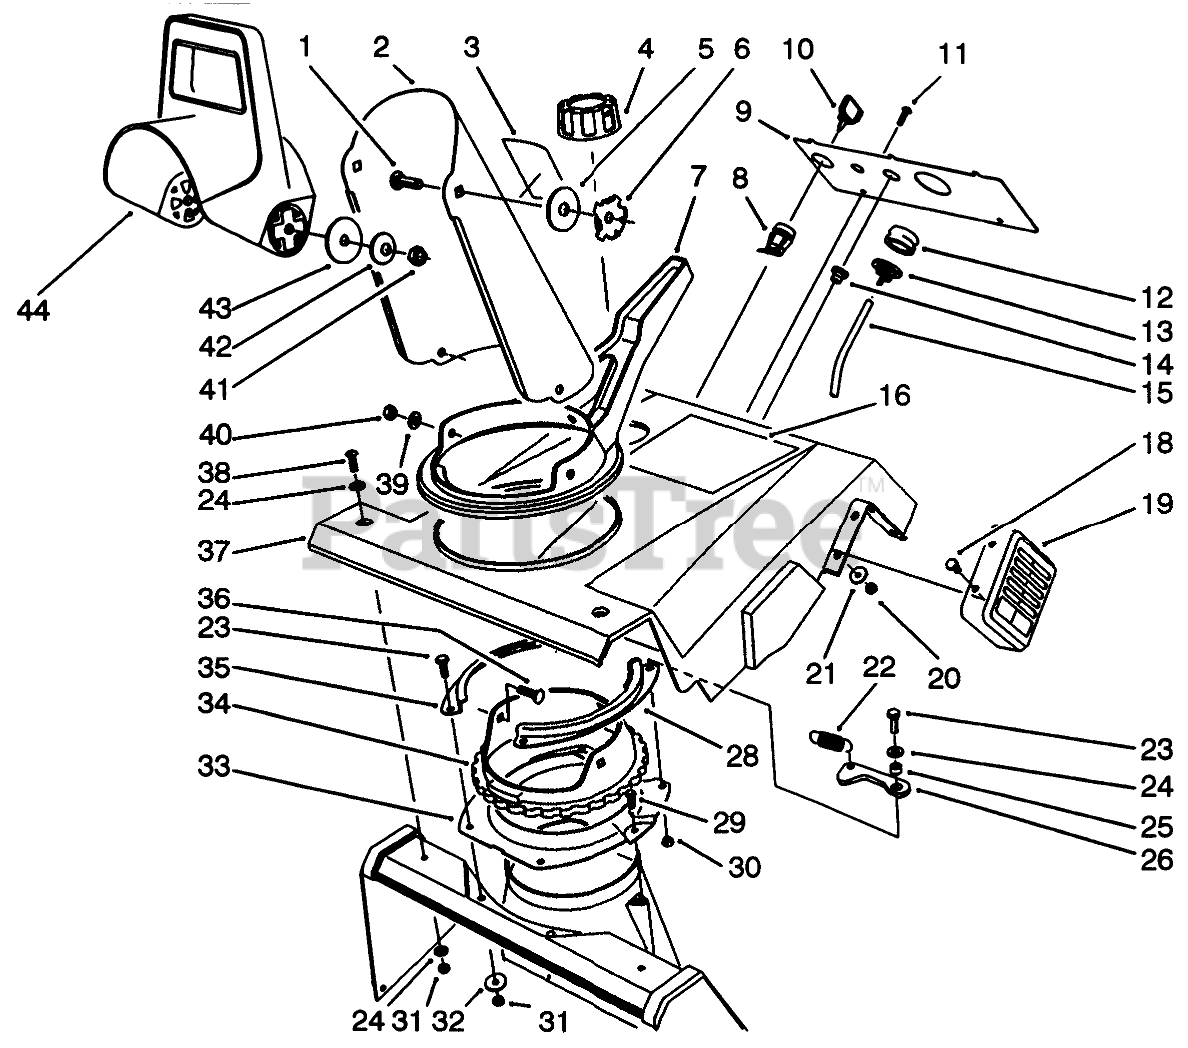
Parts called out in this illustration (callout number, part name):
1	SCREW-CARR
2	Discharge Chute Assembly (Incl. Ref. #3)(Model No. 38195)
3	Decal-Danger
4	CAP-FUEL ASM
5	WASHER-RUBBER
6	PLATE-FRICTION
7	CHUTE - HANDLE
8	SWITCH
9	CNTRL PANEL/SILK SCREEN
10	KEY-IGNITION
11	SCREW-SHWH, THREAD FORMING
12	BULB-PRIMER
13	BODY-PRIMER
14	GUIDE-ROPE, STARTER
15	HOSE-PRIMER
16	DECAL - CCR 1000E
18	SCREW-HWH
19	Guard-Muffler
20	NUT-LOCK, NI
21	WASHER-FLAT
22	OBS DETENT SPRING
23	SCREW-HH
24	WASHER-FLAT
25	SPACER-BLADE, ROTOR
26	DETENT
28	Retainer-Chute Ring
29	SCREW-PLASTITE
30	NUT-LOCK, NI
31	NUT-LOCK, NI
32	WASHER-FLAT
33	Ring-Chute Support
34	GEAR RING, CHUTE
35	Retainer-Chute Ring
36	SCREW-CARR
37	UPPER SHROUD
38	SCREW-PPH
39	WASHER-FLAT
40	NUT-KEPS
41	NUT-LOCK, NI
42	WASHER-BELLEVILLE
43	WASHER-FLAT
44	CHUTE-DEFLECTOR
